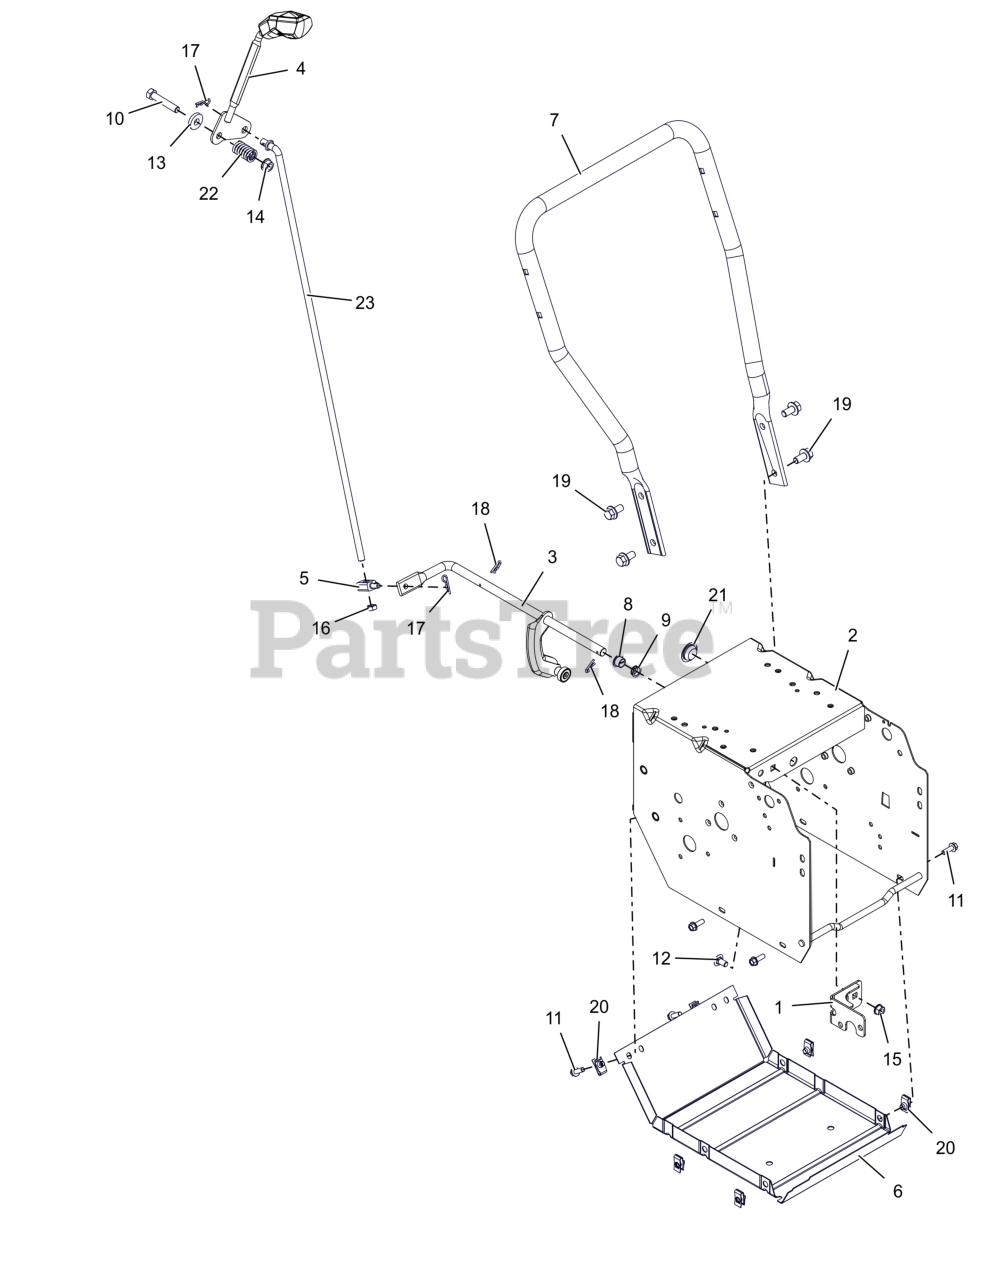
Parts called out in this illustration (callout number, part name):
1	WELDMENT, FRAME BRACKET
2	WELDMENT, FRAME - DELUXE 16"
3	ARM, SHIFT-SMALL DASH (ASSY)
4	ASM, LEVER W/KNOB-SM DASH SPEED
5	PIVOT,SHIFT ROD .375-16(TRUNN)
6	COVER, BOTTOM
7	HANDLEBAR, LOWER - SM DELUXE
8	BUSHING, POLYLINER-.50 SPLIT
9	BUSHING, POLYLINER-.50 SNAPIN
10	BLT,HEX .38-16X2.00 G5 ZCC
11	BLT, HWH .25-20X.75 G5 ZCC
12	BLT, RHSSN .31-18X.625 G5 ZCC
13	WSHR, FLT .406X1.00X.188 ZCC
14	NUT-LK-TOP-FLG .38-16 ZC120
15	NUT-LK-TOP-FLG .312-18 GF ZCC
16	NUT-JAM .375-16 G2 ZCC
17	PIN, HAIR #213 .08X1.19 ZCC
18	CLIP, SPRING
20	NUT-RTNR .25-20X.56
21	PLUG, HOLE - .875" NYLON
22	SG-COMP .125X.781X1.250
23	ROD, SHIFT - COMPACT
